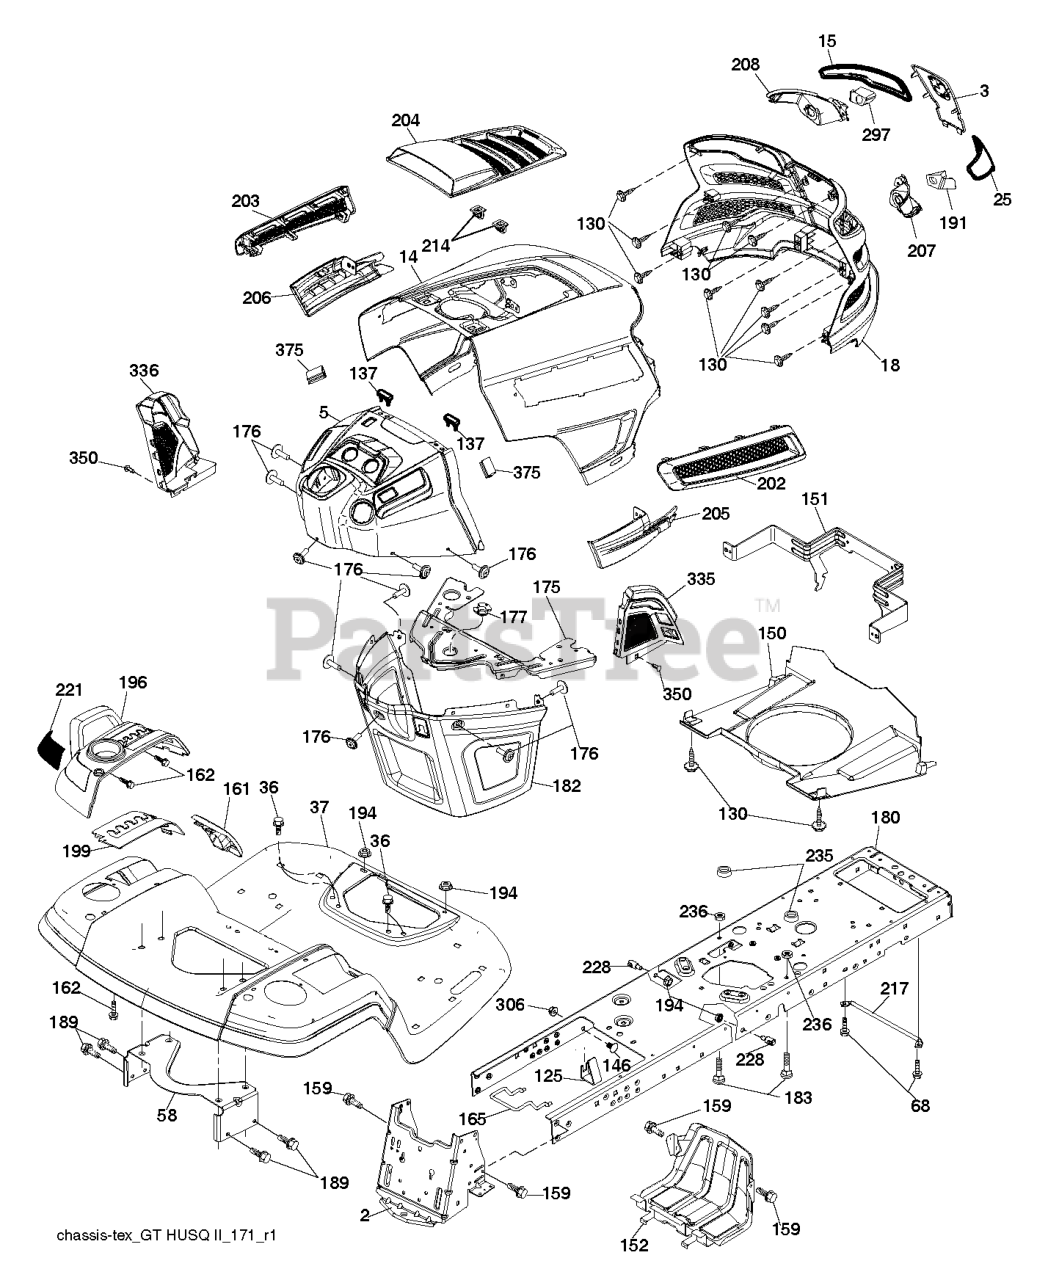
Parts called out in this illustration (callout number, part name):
2	DRAWBAR.STGT
3	APPLIQUE.SUBASM.GT.HUSQ.II
5	DASH.UPP.GT2.DR.PTO.DCKLFT.MC
14	HOOD.ASM.HUSQVARNA.GT.TEX.422
15	LENS.HEADLIGHT.LH.GTII.2011
18	GRILLE.SUBSTRATE.2011.
25	LENS.HEADLIGHT.RH.GTII.2011
36	SCREW 5/16"
37	FENDER.PNT.TX.GT.CH/FW/DL.HUSQ
58	BRKT.SUPPORT.FNDR/TANK
68	Screw 5/16-18 x 1/2 Hex, Self Tapping 5/16-18 x 1/2
125	CLIP.FUEL.LINE
130	SCREW.#10 X 0.750.BOS
137	BUMPER DASH
146	BOLT.RDHD.SHT.SQNK.3/8-16X5/8
150	AIR.DUCT.GTV.BLACK
151	BRACKET.PIVOT.HOOD.GT.HUSQ.II
152	SHIELD.BROWNING.PNT.GT.V2
159	SCREW, 3/8-16X3/4
161	CONSOLE.WINDOW.FUEL.HUSQ.GT
162	SCREW.HI-LO.CONSOLE
165	SUPPORT.TANK.REAR.B/TE
175	PLATE.CROSSMEMBER.HUSQ
176	SCREW.#10-24X5/8.RN.QU
177	BUSHING STEERING
180	CHASSIS.TEX.BOLTED
182	DASH.LOWER.COMMON.12V.ADAPTOR
183	BOLT.5/16-18X1-1/4 FULL THD
189	SCREW
191	INSERT.REFLECTIVE.RH.HUSQ.GTII
194	NUT LOCK HEX FLANGE 5/16-18
196	CONSOLE.ASM.DECKLIFT.HUSQGT.DL
199	PLATE.DECK.LIFT.HUSQVARNA.GT
202	VENT.SIDE.RH.GT.HUSQ.II.
203	VENT.SIDE.LH.GT.HUSQ.II.498
204	VENT.TOP.HUSQ.GT2
205	SIDE.TRIM.RH.GT.HUSQ.II
206	SIDE.TRIM.LH.GT.HUSQ.II.GRAY
207	BEZEL LIGHT.RH.GT.II.MYLAR
208	BEZEL LIGHT.LH.GT.II.MYLAR
214	CLIP.RETAINER.TINNER.
217	ROD.PIVOT.HOOD
221	REFLECTOR.LH.TEX GT HU
228	STUD.FASTNER.W/ANTI-ROTATE
235	SPACER FENDER
236	NUT.CENTERLOCK.5/16-
297	INSERT.REFLECTIVE.LH.HUSQ.GTII
306	NUT LOCK FLG 3/8-16 UNC
335	COVER.LOWER.DASH.RH.BLACK
336	COVER-LH.LOWER.DASH.GT2.BLACK
350	KIT GUARD BRUSH
375	BUMPER CLIP-ON. DASH 1"
